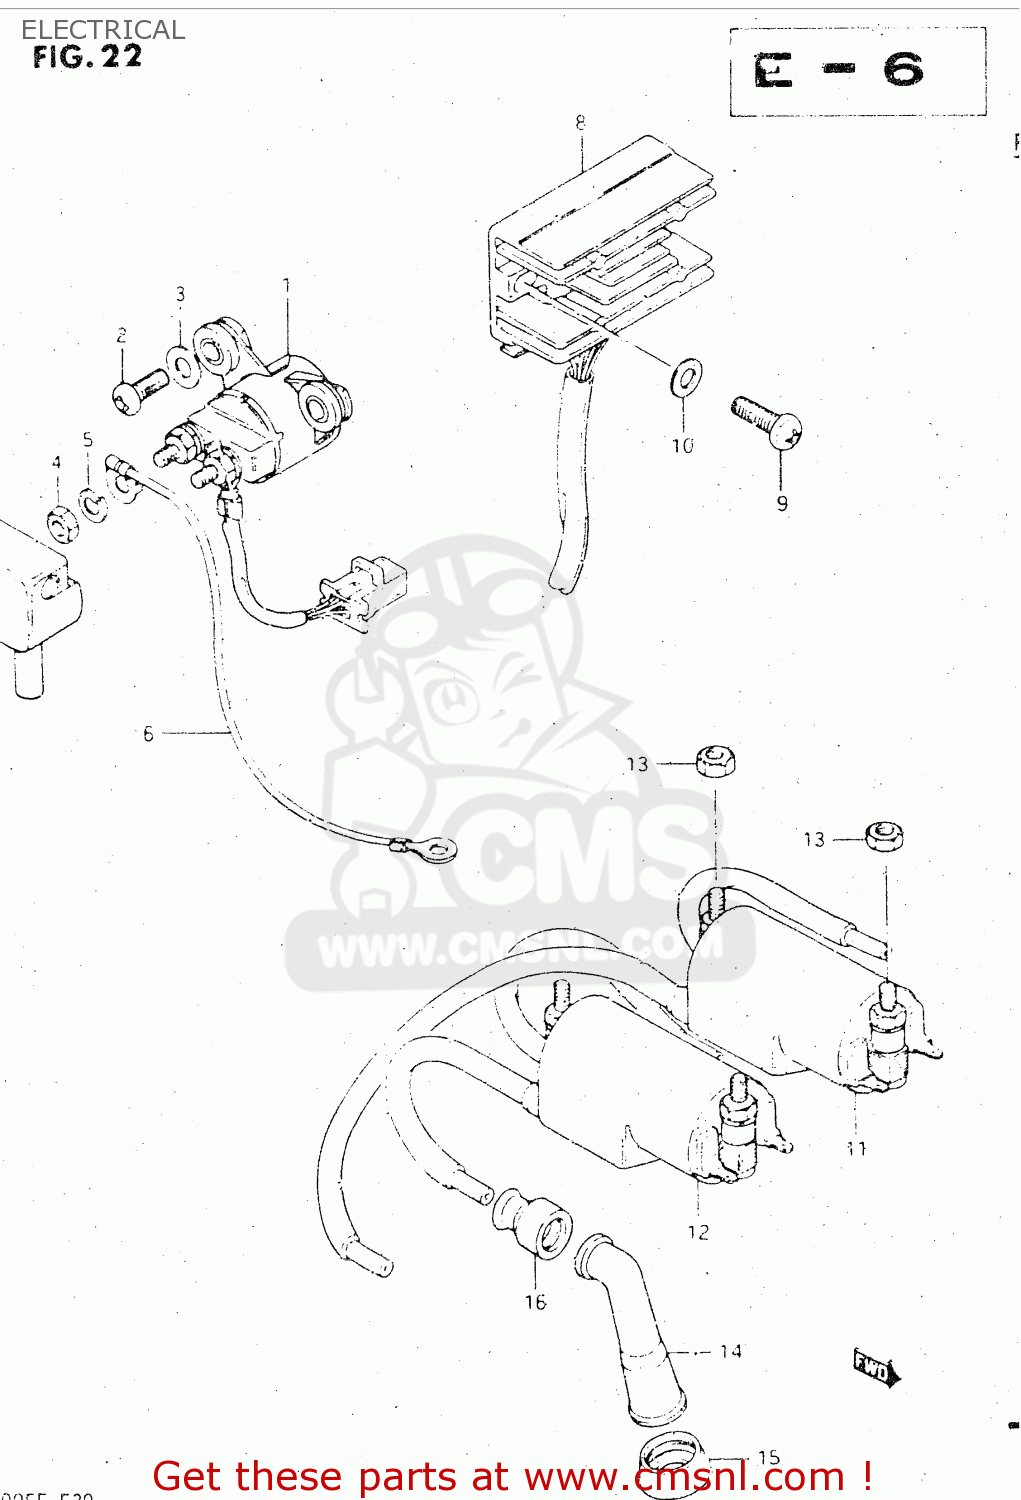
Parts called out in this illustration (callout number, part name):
1	RELAY,STARTER SWITCH
2	SCREW
3	WASHER
4	NUT
5	WASHER,LOCK
6	WIRE,STARTER MOTOR LEAD
7	CAP,STARTER RELAY TERMINAL
8	RECTIFIER ASSEMBLY
9	SCREW
10	WASHER, LOWER
11	COIL ASSEMBLY,IGNITION
12	COIL ASSEMBLY,IGNITION
13	NUT
14	CAP ASSY,SPARK PLUG
15	SEAL,SPARK PLUG CAP
16	SEAL,SPARK PLU
